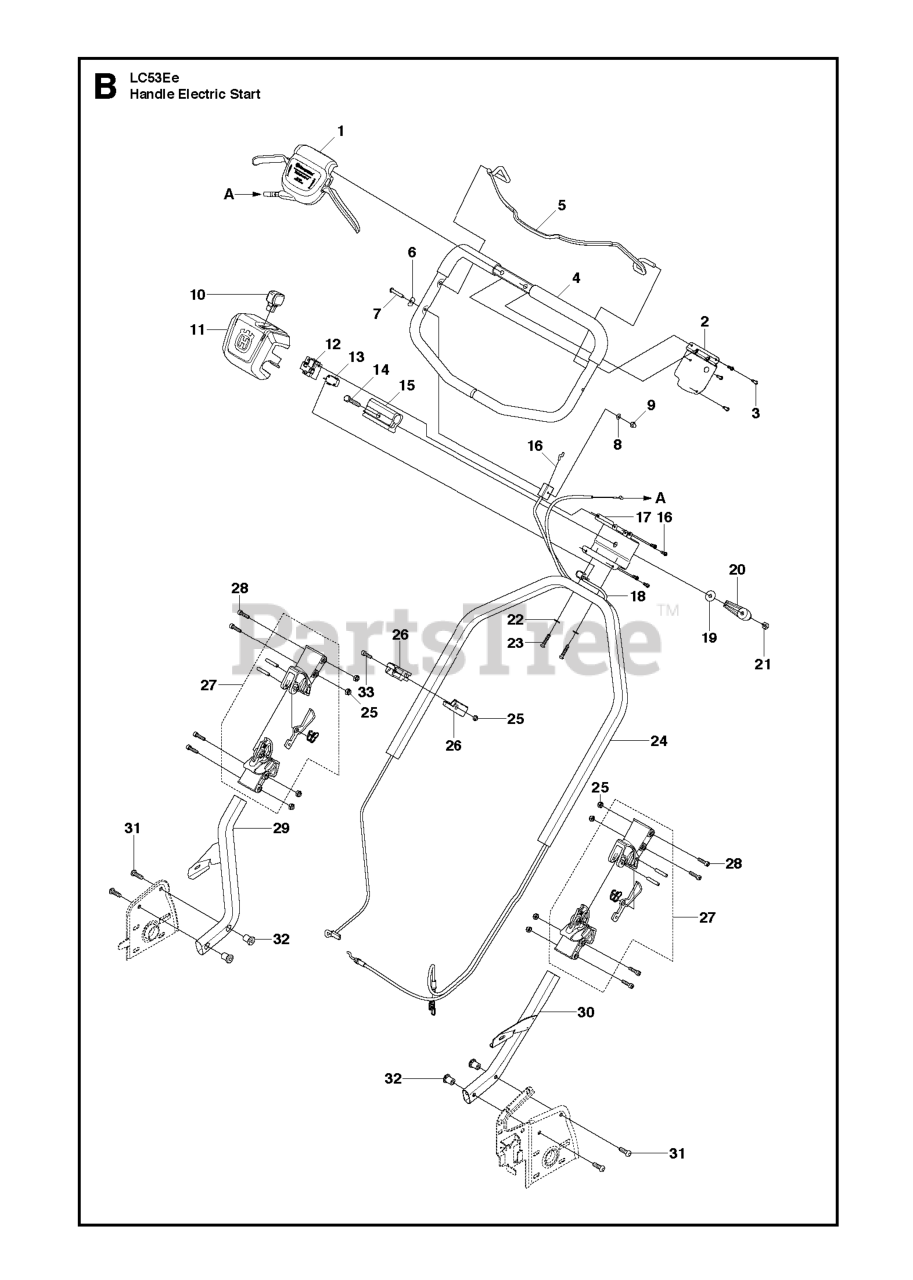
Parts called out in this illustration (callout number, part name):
8	WASHER - M6
19	WASHER - 25X8.5X2.3
28	REPL BY 725 53 74-55
33	SCREW MC6S 6X20
